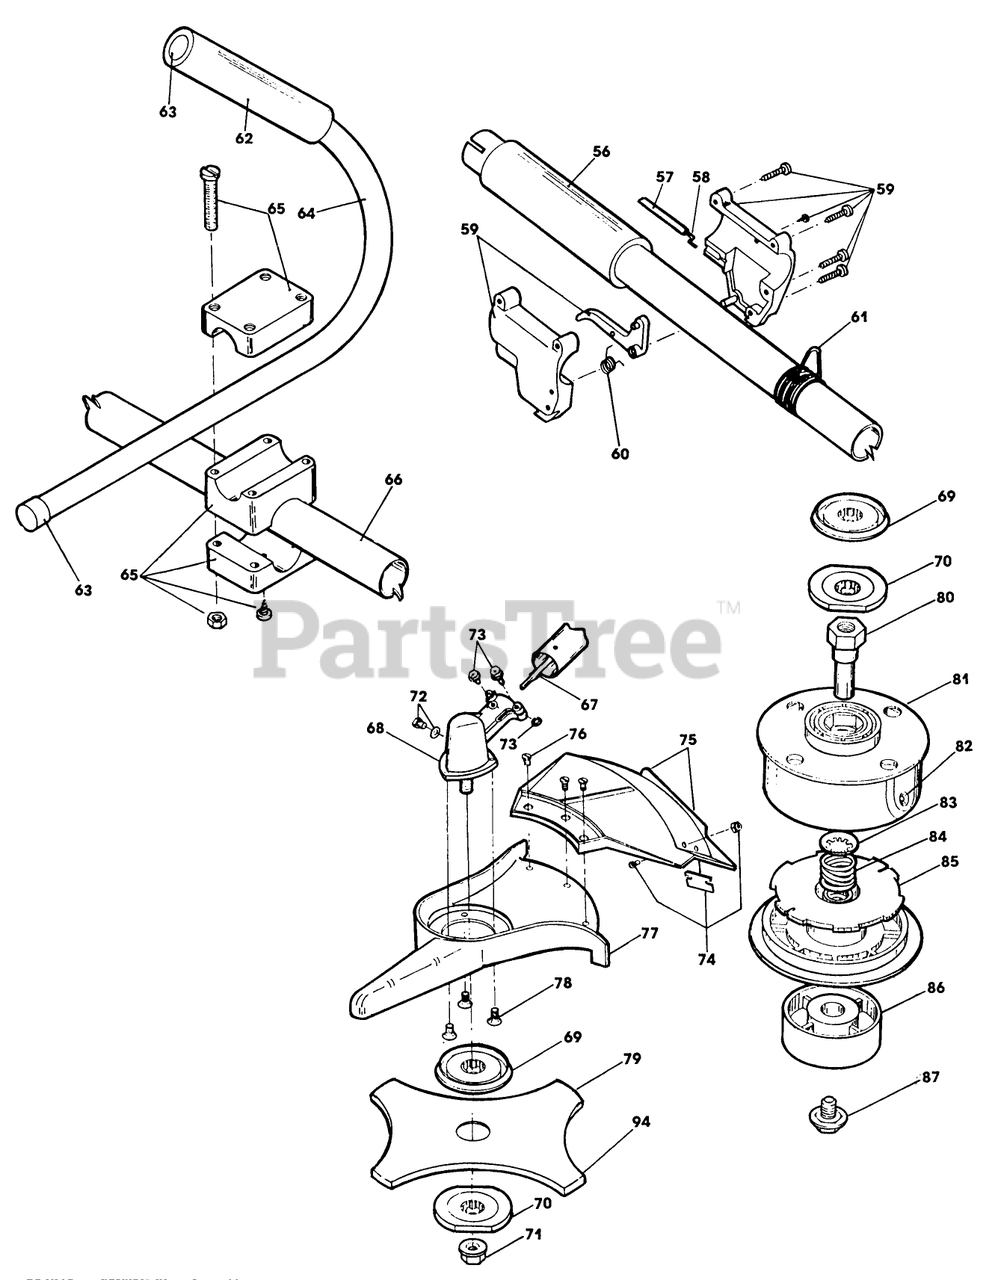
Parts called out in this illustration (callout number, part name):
58	THROTTLE CABLE WIRE
60	THROTTLE TRIGGER SPRING
62	HANDLE NITRILE GRIP
63	TUBE CLOSURE
65	HANDLE BRACKET ASM
66	DRIVE SHAFT HSG ASM
67	FLEX SHAFT ASM
68	GEAR BOX ASM
74	BLADE ASM
75	GUARD & BLADE ASM
76	GUARD MNTG SCREW ASM
77	GUARD MOUNTING SCREWS
81	OUTER SPOOL EYELET ASM
83	RETAINER
94	BLADE SAFETY GUARD
